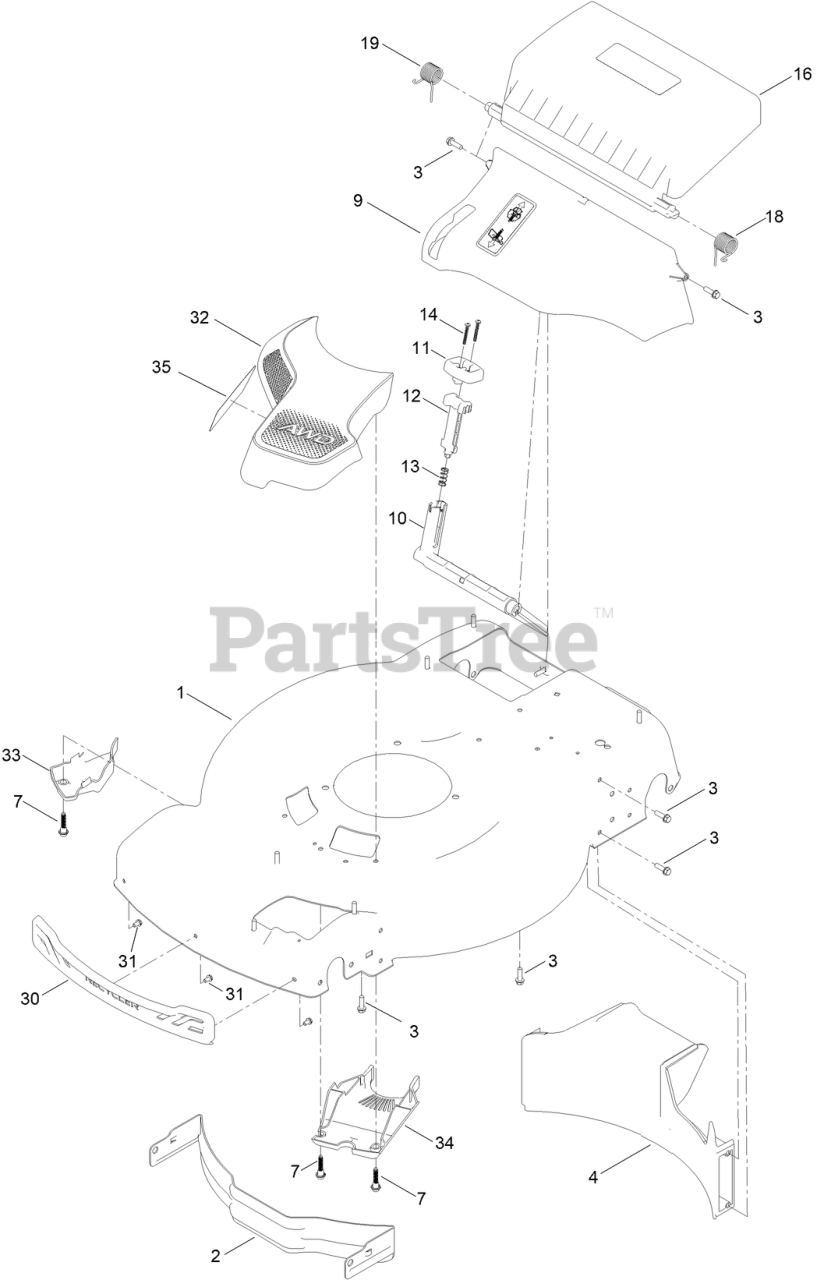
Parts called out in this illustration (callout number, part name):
1	HOUSING ASM
2	BAFFLE-FRONT
3	SCREW-PLASTITE, HWH
4	BAFFLE-REAR, RWD
7	SCREW-SHOULDER, HHF
9	ASM-CHUTE, IN MOLD
10	DEFLECTOR-RECYCLE
11	KNOB-RECYCLE
12	LATCH-RECYCLE
13	SPRING-COMPRESSION
14	SCREW-PPH
16	ASM-REAR DOOR, IN MOLD
18	SPRING-TORSION, LH
19	SPRING-TORSION, RH
30	BUMPER-FRONT
31	SCREW-PLASTIC, HWH
32	ASM-INTAKE, AWD
33	COVER-INTAKE, BOTTOM
34	COVER-BELT, LOWER (AWD)
35	DECAL-VORTEX AWD
